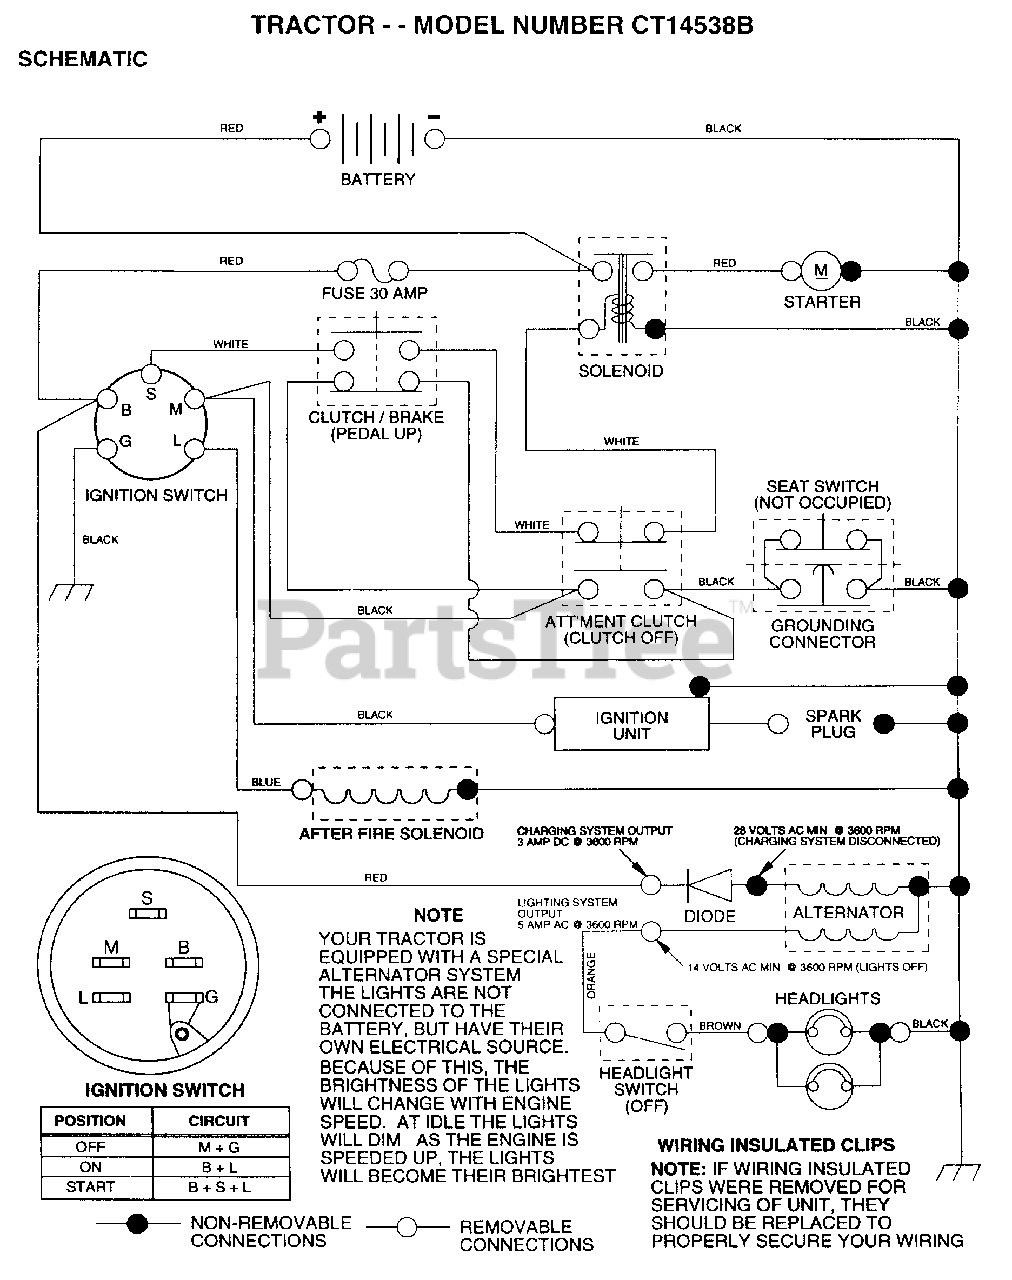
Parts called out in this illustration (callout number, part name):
1	DECAL.DASH.INST.
1	VALVE CAP
2	GRILL DECAL
2	VALVE STEM LT
4	TUBE.5.3/4.5/6
5	DECAL.INS.HD.RALL
5	"RIM ASM 6"" FRT"
6	DECAL
6	FITTING LT
7	"FLANGE, BEARING"
8	FENDER DECAL
8	"RIM AS 8"" REAR"
9	TIRE.TS2.18X8.5
10	TUBE.18X9.5-8
11	HUB CAP
12	DECAL HOOD RH RLY
13	"DECAL,STR WHL"
14	DECAL HOOD LH RLY
15	DECAL.BTRY.DANGER
16	DECAL BRAK PARK
17	DECAL
